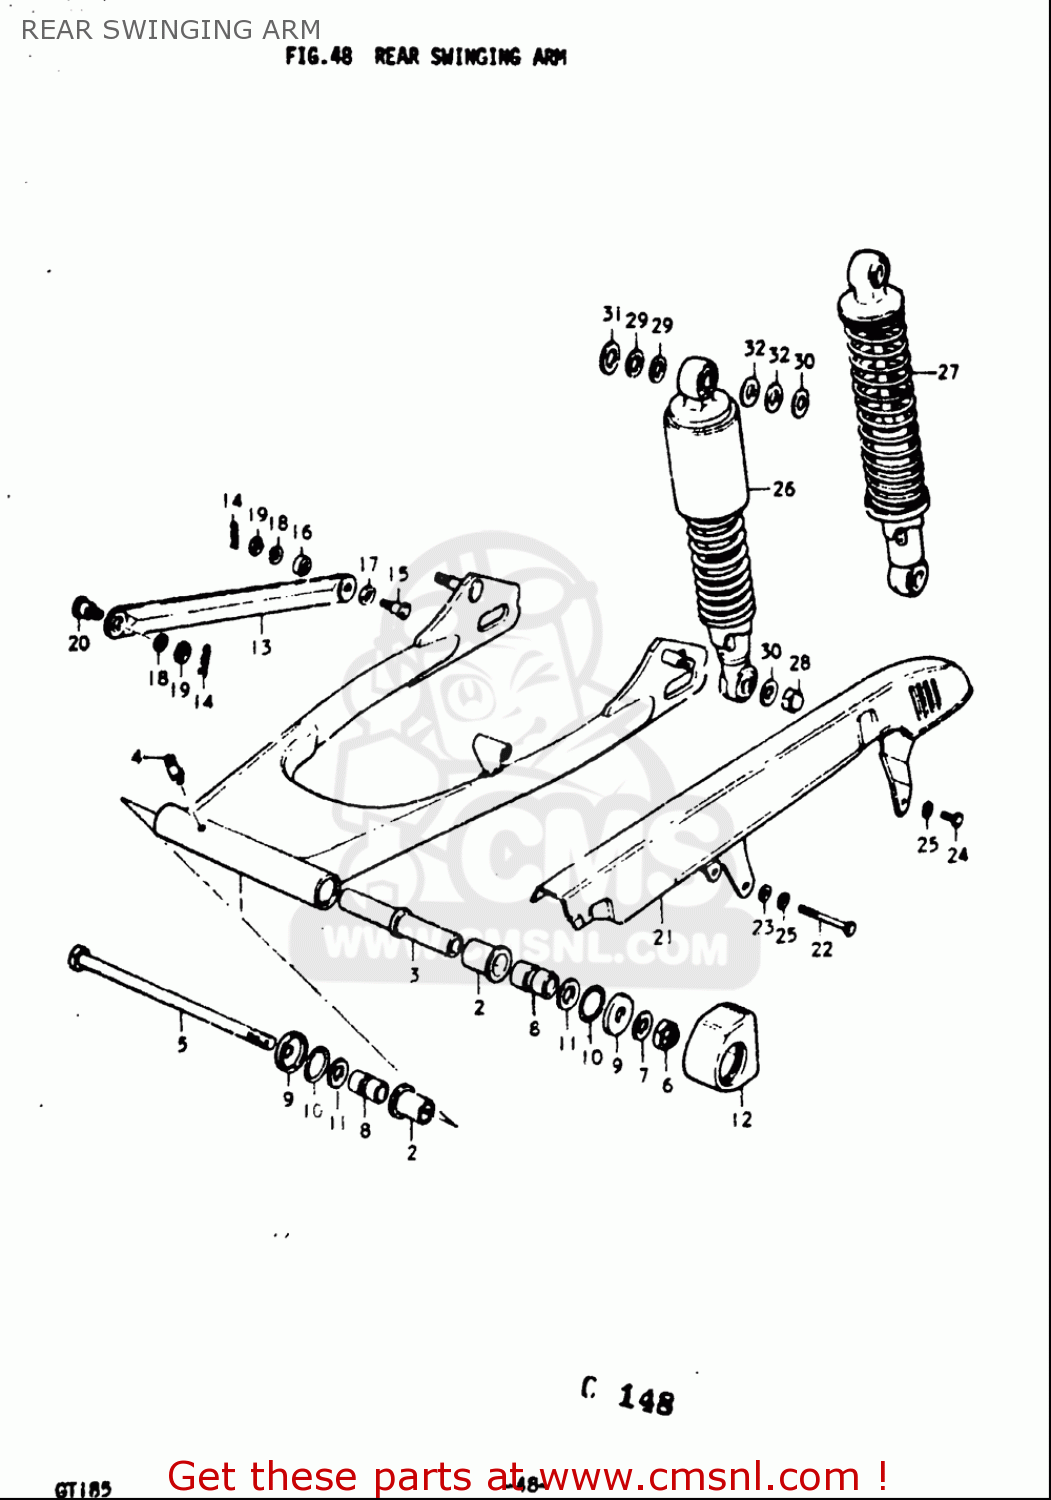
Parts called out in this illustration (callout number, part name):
2	BUSH
3	SPACER,SWING ARM,CENTER
4	NIPPLE,GREASE
5	SHAFT,PIVOT
6	NUT
7	WASHER
8	SPACER,RR SWGARM PIVOT
9	COVER,SWGARM BUSH DUST SEAL
10	O RING(D:2,ID:24.5)
11	WASHER(12.5X24X2.3)
12	BUFFER,CHAIN TOUCH DEFLECTOR
13	LINK,REAR TORQUE
14	CLIP
15	BOLT
16	WASHER
17	WASHER(8.5X26X1.6)
18	WASHER,LOCK
19	NUT
20	BOLT(8X22.5)
22	BOLT 6X45
23	WASHER
24	BOLT
25	WASHER,LOCK
26	ABSORBER ASSEMBLY,REAR SHOCK
27	ABSORBER ASSEMBLY,REAR SHOCK
28	NUT
29	WASHER
30	WASHER (10.5X24X2.3)
31	WASHER(12.5X24X3.2)
32	WASHER (10.5X25X3.2)
